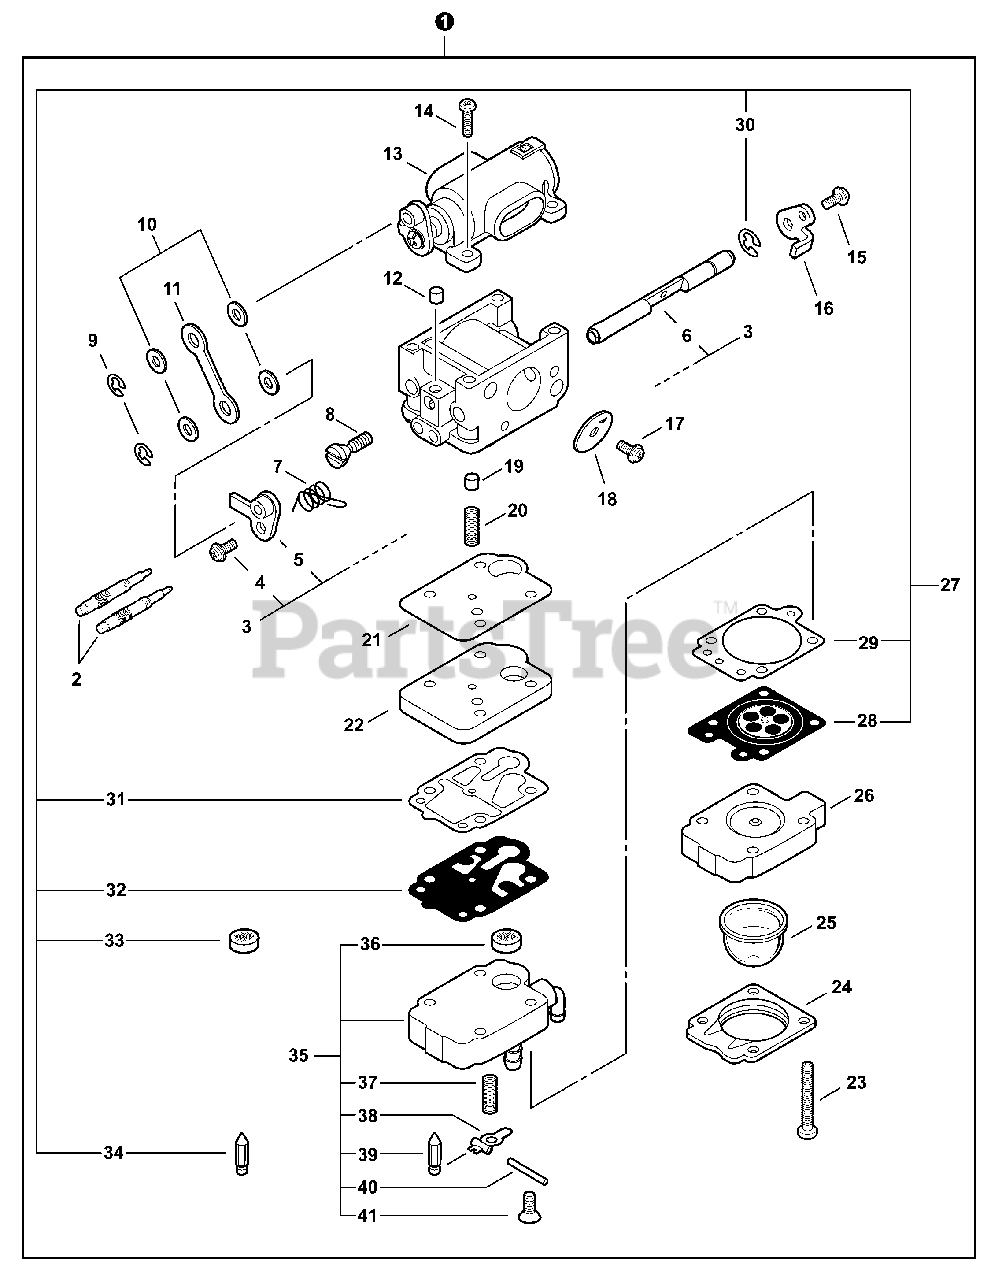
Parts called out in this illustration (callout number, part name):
1	CARBURETOR - WLA-1
2	NEEDLE, MIXTURE
3	SHAFT ASSY, THROTTLE
5	LINK ASSY, THROTTLE
6	SHAFT, THROTTLE
11	LINK, ROD
12	PLUG, FRICTION
13	VALVE ASSY, AIR
16	LEVER, CHOKE
18	VALVE, THROTTLE
19	PISTON ASSY
21	GASKET, PASSAGE
22	PLATE, PASSAGE
24	RETAINER, PURGE BULB
25	BULB, PURGE
26	BODY ASSY, PURGE
27	REPAIR KIT
28	DIAPHRAGM, METERING
29	GASKET, METERING
30	RING, RETAINING
31	GASKET, PUMP
32	DIAPHRAGM, PUMP
33	STRAINER
34	VALVE, INLET NEEDLE
35	BODY ASSY, PUMP
36	STRAINER
37	SPRING, METERING LEVER
38	LEVER, METERING
39	VALVE, INLET NEEDLE
40	PIN, METERING LEVER
